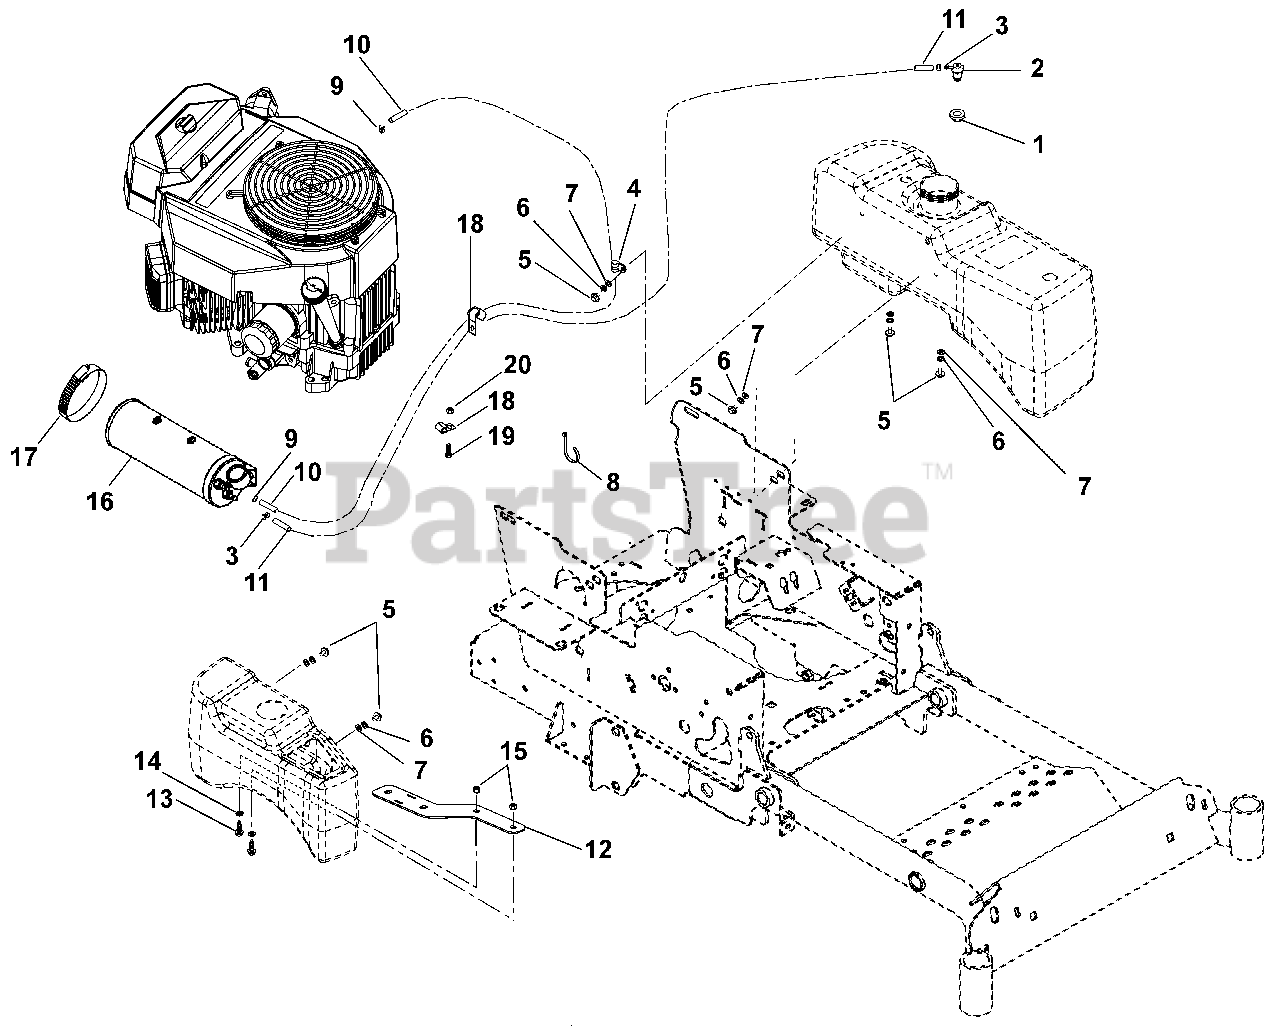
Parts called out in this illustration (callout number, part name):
2	Valve
3	Hose, Clamp
5	Bolt, .31-18 x .62
6	Washer, Locking .31 x .078 Regular
7	Washer, Flat Steel .38 x .875 x .083
8	Tie, Cable LG 5.50
9	Clamp, Spring .188
10	Hose, Fuel .18"
11	Hose, Fuel .25"
12	Plate, Canister Mount
13	Screw, Tapping .25-20 x 1.50 Hex Washer Head Thread Rolling
14	Washer, Flat Steel .281 x 1.000 x .063
15	Nut, Locking Nylon Flange .25-20
16	Canister, Carbon 9.36 Cap
17	Clamp, Hose Worm 2.3/3.2 Stainless Steel #44
18	Clamp, Cushioned Steel
19	Bolt, Hex .38-16 x 1.00 Grade 5
20	Nut, Locking Nylon Flange .38-16
